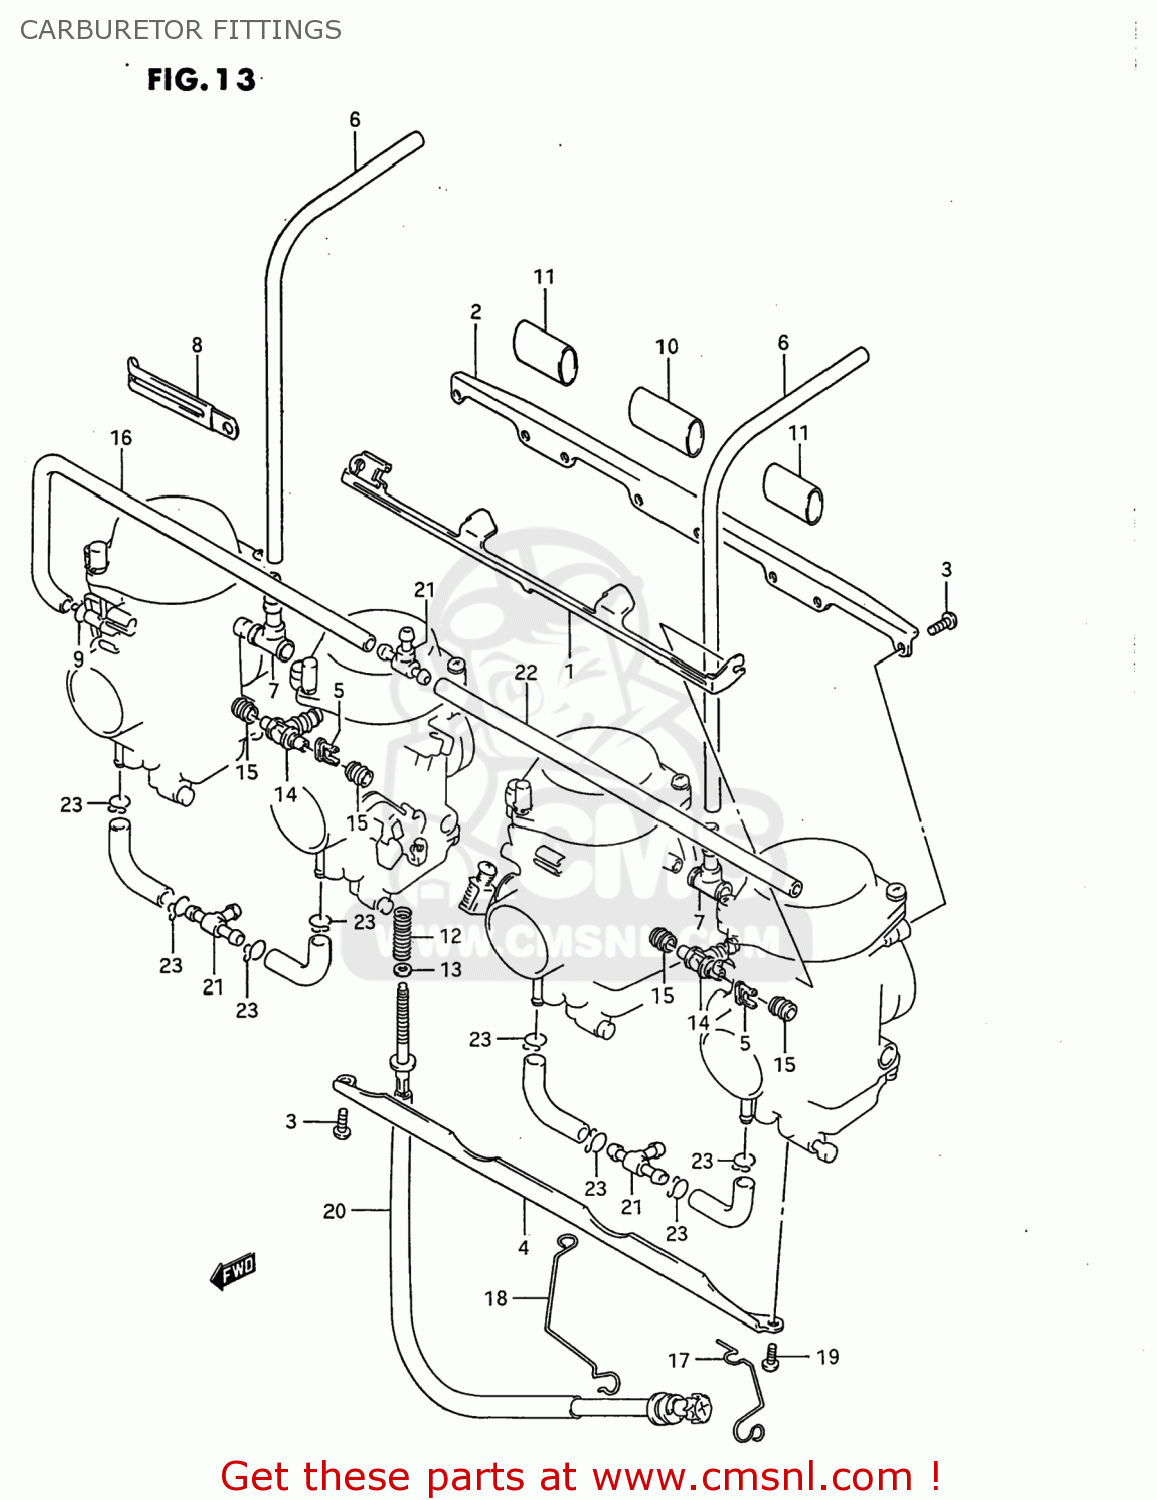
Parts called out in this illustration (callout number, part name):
1	LEVER
2	PLATE
3	SCREW
4	PLATE
5	HOLDER
6	HOSE(7X10.2X600)
7	HOSE
8	CLAMP(L:80)
9	CLIP
10	HOSE(16X19X100)
11	HOSE(16X19X100)
12	SPRING
13	WASHER
14	NIPPLE
15	SEAL
16	HOSE
17	CLIP
18	CLIP
19	SCREW
20	ADJUSTER
21	NIPPLE
22	HOSE(5X9X600)
23	CLIP
